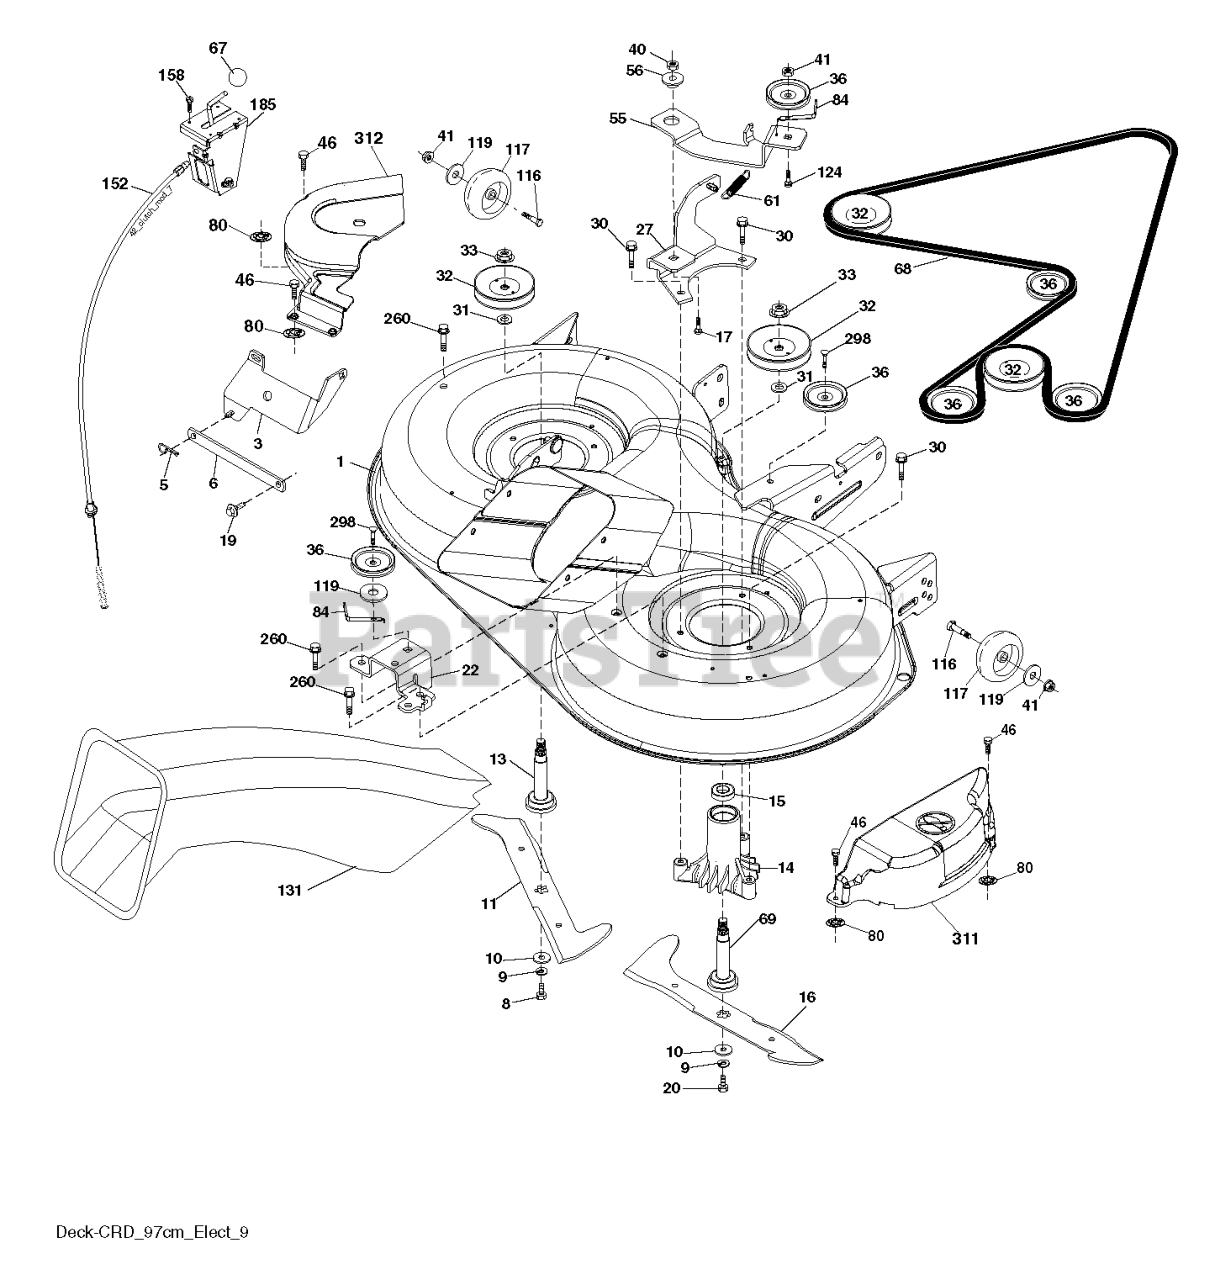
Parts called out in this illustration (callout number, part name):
1	DECK.WLDT.97.CRD.2GWB.
3	BRACKET.ASM.BAR.SWAY.CHASS
5	RETAINER-SPRNG RB
6	BAR.SWAY.92.CRD
8	BOLT.3/8-24X1.25 GR8
9	LOCKWASHER
10	WASHER.BLADE
11	BLADE.3N1.LH.CRD.97
13	SHAFT ASM VENT
14	HOUSING.MANDREL.VENTED (MACHD)
16	BLADE.3N1.RH.CRD.97
17	BOLT.3/8-14X1.25
19	BOLT SHD 5/16-18
20	BOLT.3/8-24X1.25GR8. LHTHRD
22	BRACKET.SUPT.IDLER.REAR.RH
27	BRACKET.ASM.SUSP.REAR.RH.
30	SCREW, WASHER HEAD
31	WASHER.SPACER.MANDREL
32	PULLEY MANDREL
33	NUT.FLANGE.LOCK.TOP
36	PULLEY.IDLER.4.25
41	NUT LOCK FLG 3/8-16 UNC
46	SCREW.1/4-20X5/8
55	ARM.IDLER.92 CRD.2006
56	SPACER.RETAINER.MOWER
61	SPRING
67	KNOB T (3/8 HOLE)
68	BELT.DRIVE.CRD.97.2010
69	SHAFT.ASM.W/LWR.BRG.RH.THREAD
80	PALNUT 1/4
84	KEEPER, BELT IDLER
116	BOLT.SHOULDER.3/8-16X3-5/8.
117	RP WHEEL. GUAGE RALLY
119	WASHER
124	BOLT.3/8-16X1.50
131	CHUTE BAGGER
158	SCREW
185	HEAD ASM. CABLE CLUTCH
260	SCREW 3/8-16X1/2
298	SCREW LT
311	97.CRD.RH.MANDREL.COVER
312	OVER.MANDREL.LH.CRD
